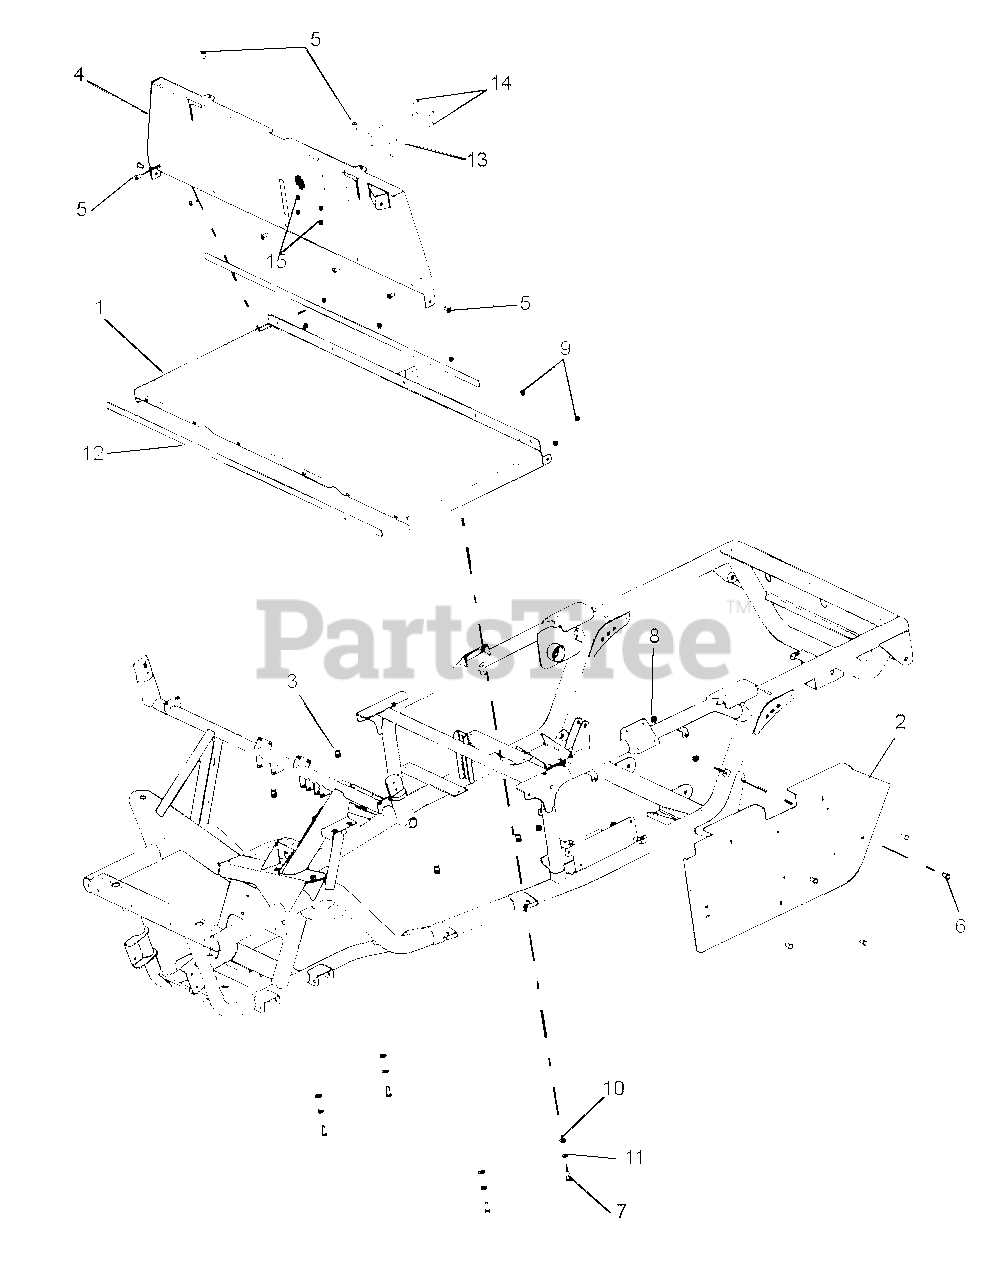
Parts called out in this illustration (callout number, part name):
1	FLOOR WIDE WELDMENT
2	SIDE PANEL, WIDE
3	NUTZERT, 5/16-18 X .667 HEX
4	KICK PANEL WLDMNT
5	SCREW, MACHINE .25-20 X .75 TXTR YWZC
6	BOLT, HEX 5/16-18 X 3/4 GR5 YWZC
7	BOLT, HEX 5/16-18 X 1 GR5 YWZC
8	NUT, HEX TOP LOCK FLANGE .312-18YWZC
9	NUT, LOCKING TOP FLANGE 1/4-20 YWZC
10	WASHER, FLAT 5/16 HARDENED ASTMF436
11	WASHER, LOCK SPRING 5/16 YWZC
12	FOAM RUBBER 3/16 X 3/4 THK WITH PSA 52.5" Lg.
13	BRACKET, MODULE EPA FUSE/RELAY (600 Series Main Harness) *
14	TTHMS 1/4-20 X 3/4 YWZC
15	NUT, HEX FLANGE TL 1/4-20 YWZC
